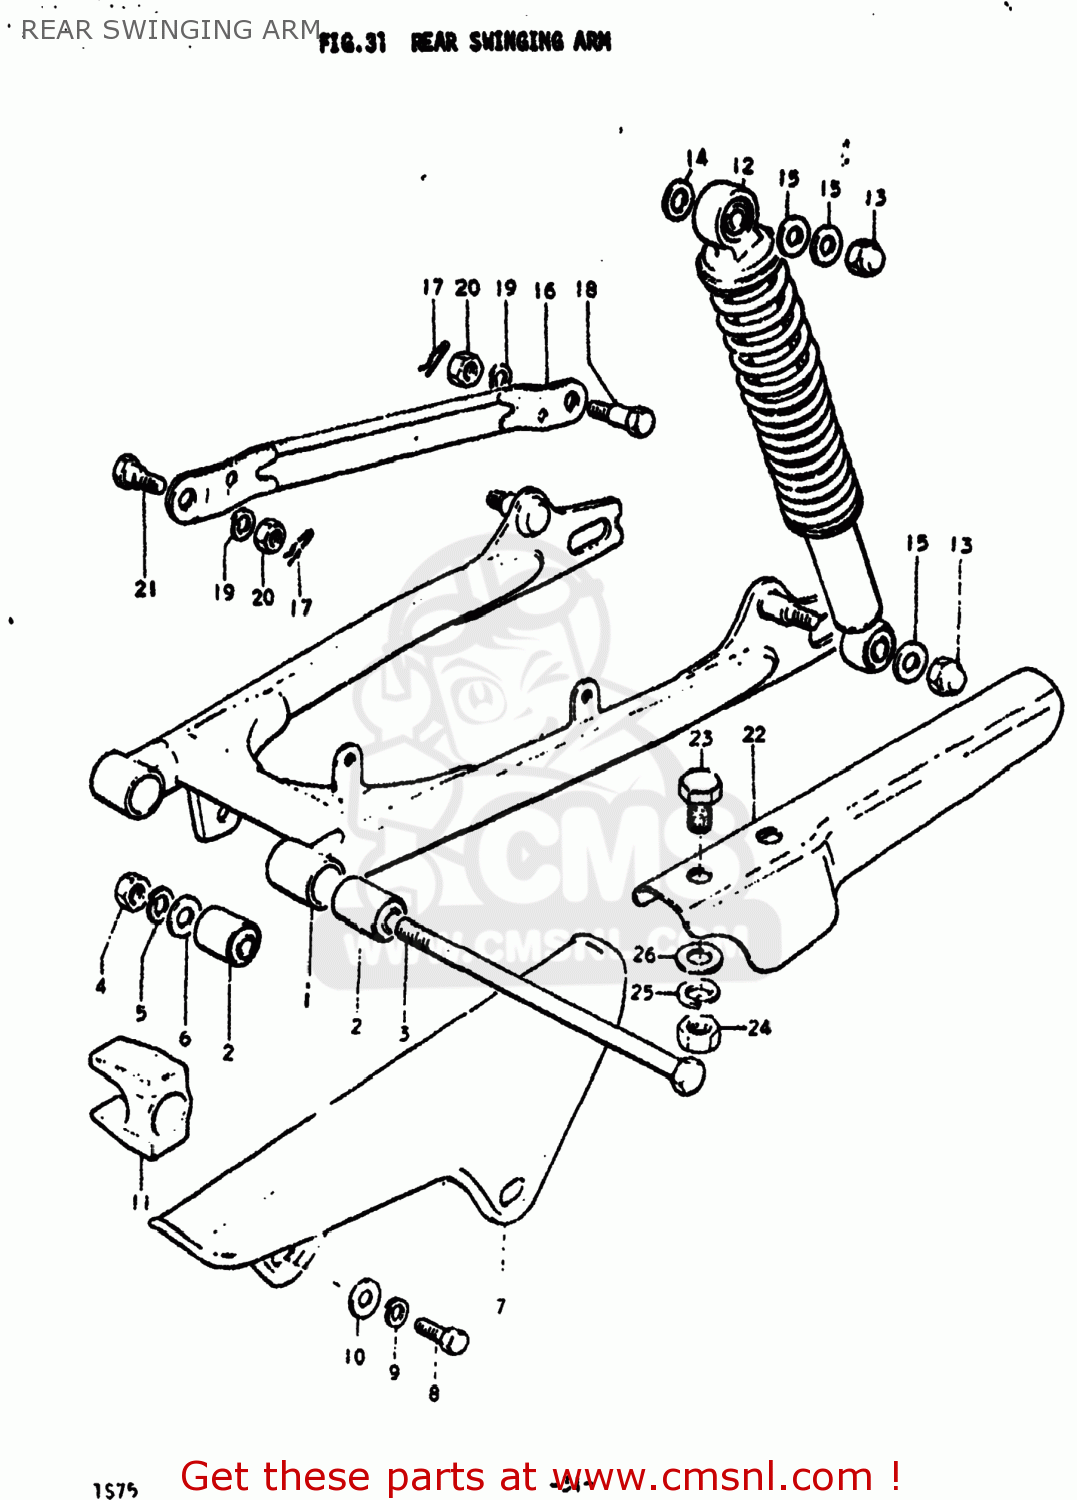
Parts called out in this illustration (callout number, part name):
1	SWING ARM ASSEMBLY,REAR
2	BUSHING(10X23X35)
3	SHAFT,RR SHOCK ABSORBER UPR
4	NUT
5	LOCK WASHER
6	WASHER
7	CASE,CHAIN
8	BOLT
9	LOCK WASHER
10	WASHER
11	BUFFER,CHAIN TOUCH DEFLECTOR
12	ABSORBER ASSEMBLY,REAR SHOCK
13	NUT
14	WASHER
15	WASHER
16	TORQUE LINK,REAR
17	CLIP
18	BOLT(8X26.5)
19	LOCK WASHER
20	NUT
21	BOLT(8X22.5)
23	BOLT
24	NUT
25	LOCK WASHER
26	WASHER
